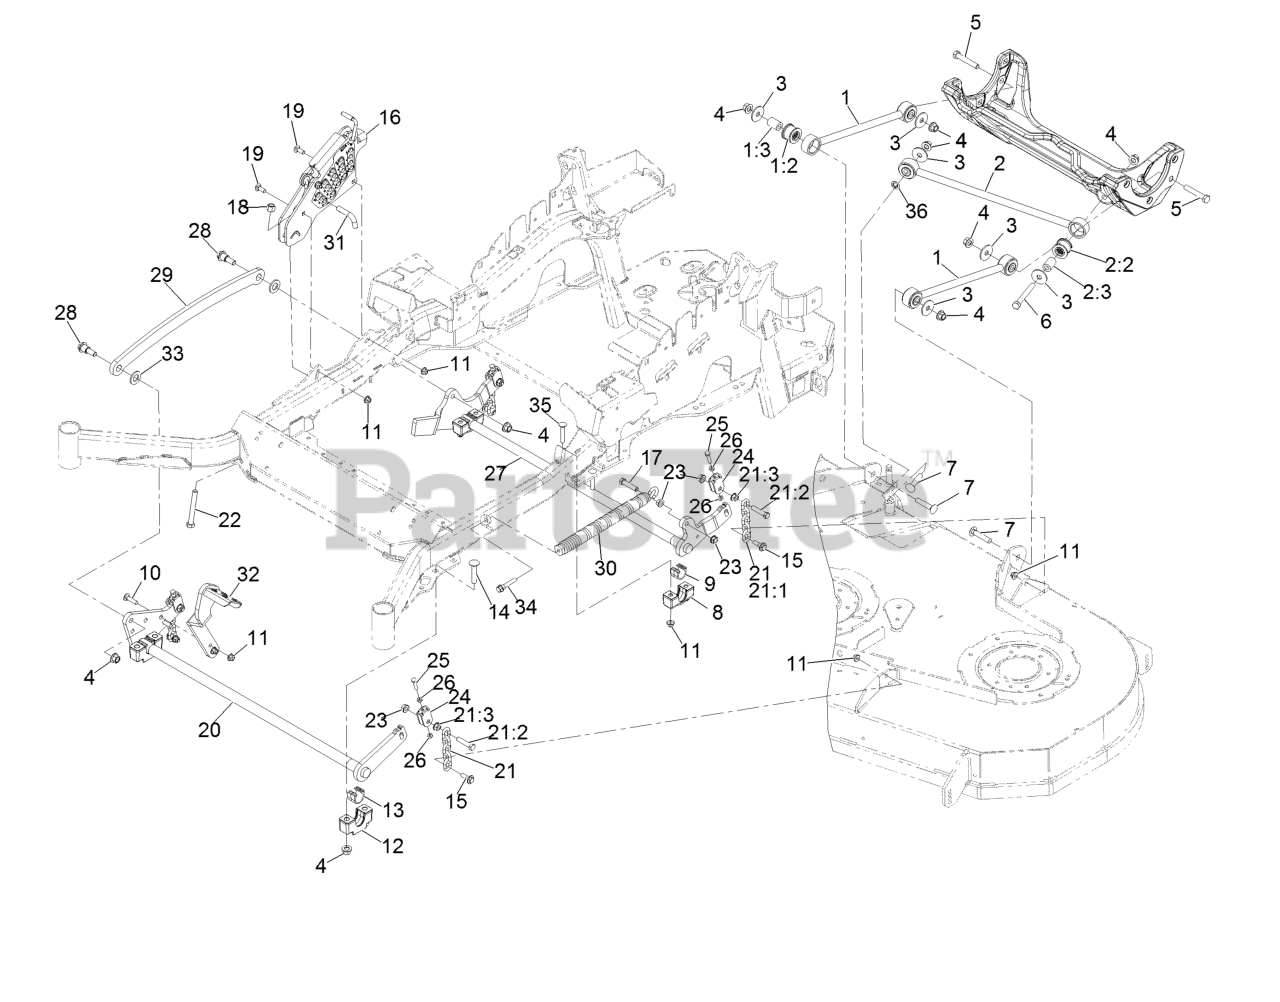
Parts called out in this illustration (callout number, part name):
1	Deck Strut ASM
1:2	Bushing-Suspension, Rubber
2	Panhard Rod ASM
2:2	Bushing-Suspension, Rubber
4	Nut-Lock 1/2-13
5	Screw-HH 1/2-13 X 3
6	Screw-HH 1/2-13 X 4
7	Bolt-Carriage 1/2-13 X 2 1/2
8	Support-Cross Shaft, Bearing Rear
9	Bearing-Cross Shaft, Rear
10	Bolt-Carriage 3/8-16 X 1 1/2
11	Nut-Nyloc 3/8-16 Flg
12	Support-Cross Shaft, Bearing
13	Bearing-Cross Shaft, Front
14	Bolt-Carriage 1/2-13 X 2 1/2 Spl Neck
15	Screw-Hex Flange 3/8-16 X.80
16	HOC ASM
17	Screw-HH 7/16-14 X 2
18	Nut-Nyloc 1/2-13
19	Bolt-Carriage 3/8-16 X 1
20	Decklift-Front
21	Deck Lift Chain ASM
21:1	Chain-Lift, Deck
21:2	Screw-HH 7/16-14 X 2
21:3	Nut-Whizlock 7/16-14
22	Bolt-HH 1/2-13 X 4 Tap
23	Nut-Whizlock 7/16-14
24	Yoke-Adjust, Deck
25	Screw-HH 5/16-18 X 1 1/4
26	Nut-Jam 5/16-18
27	Lift-Deck, Rear
28	Screw-Shoulder HHF 1/2-13 X 1.12
29	Link-Lift, Deck
30	Spring-Extension
31	Pin-HOC
32	Lever-Foot
33	Washer-3/4 SAE
34	Screw-Shcs 3/8-16 X 2.212
35	Bolt-Carriage 3/8-16 X 2 1/4
36	Nut-Push
